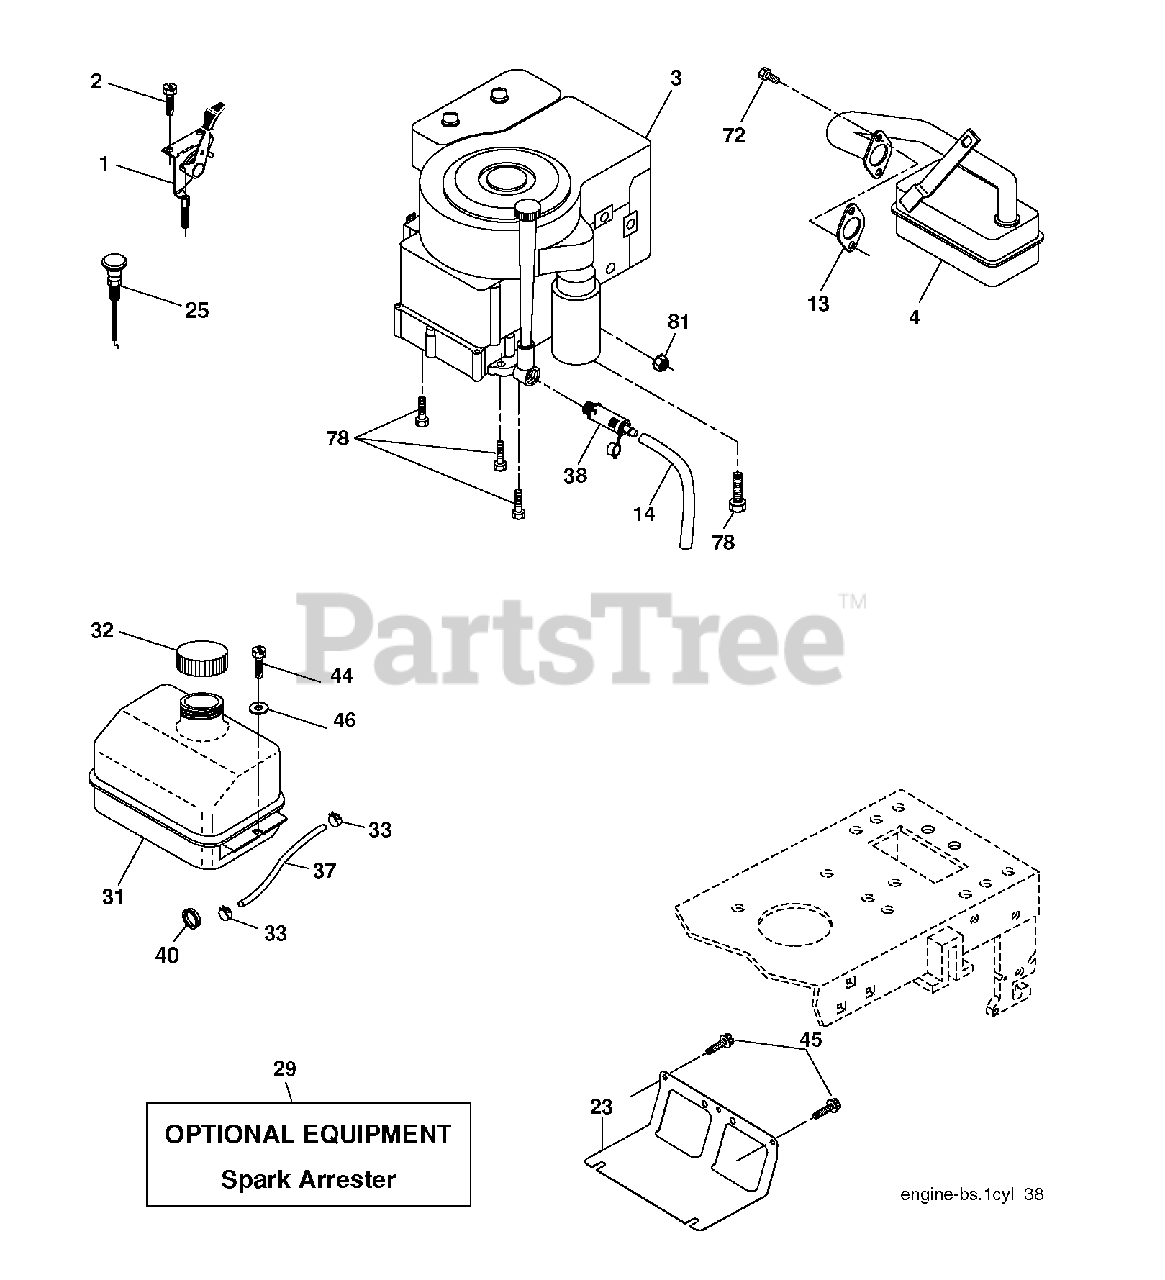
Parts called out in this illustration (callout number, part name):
1	CONTROL TH/CH FLAG
2	SCREW
13	REPL BY 532 27 22-93
14	TUBE, DRAIN OIL ASM.
23	SHEILD.BROWNING.DBR.GUARD
29	ARRESTER SPARK (OPTIONAL)
32	FUEL CAP
33	HOSE CLAMP
37	LINE.FUEL.20
38	PLUG DRAIN OIL EASY
40	GROMMET T
44	SCREW HEXWSHR 1/4-20X3/4
45	SCREW, 3/8-16X3/4
72	SCREW.SOCKET HD.5/16-1
78	SCREW.3/8-16
81	NUT
